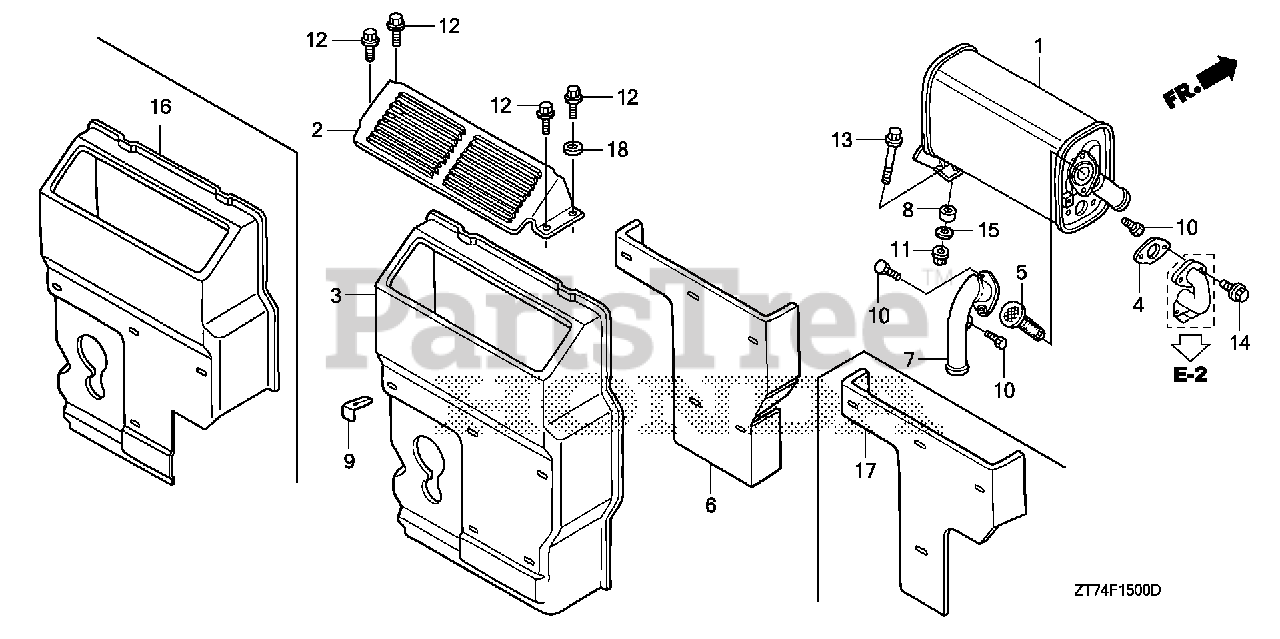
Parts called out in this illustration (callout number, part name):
1	MUFFLER
2	PROTECTOR, MUFFLER (UPPER)
3	PROTECTOR, MUFFLER (LOWER)
4	GASKET, EX. PIPE
5	ARRESTER, SPARK
6	INSULATOR, MUFFLER PROTECTOR
7	PIPE, EX. TAIL
8	WASHER, WHEEL (6MM)
9	CLIP, INSULATOR BIND
10	BOLT, RECESSED (5X8)
11	NUT, FLANGE (6MM)
12	BOLT, FLANGE (6X10)
13	BOLT, FLANGE (6X30)
14	BOLT, FLANGE (8X20)
15	WASHER, PLAIN (6MM)
